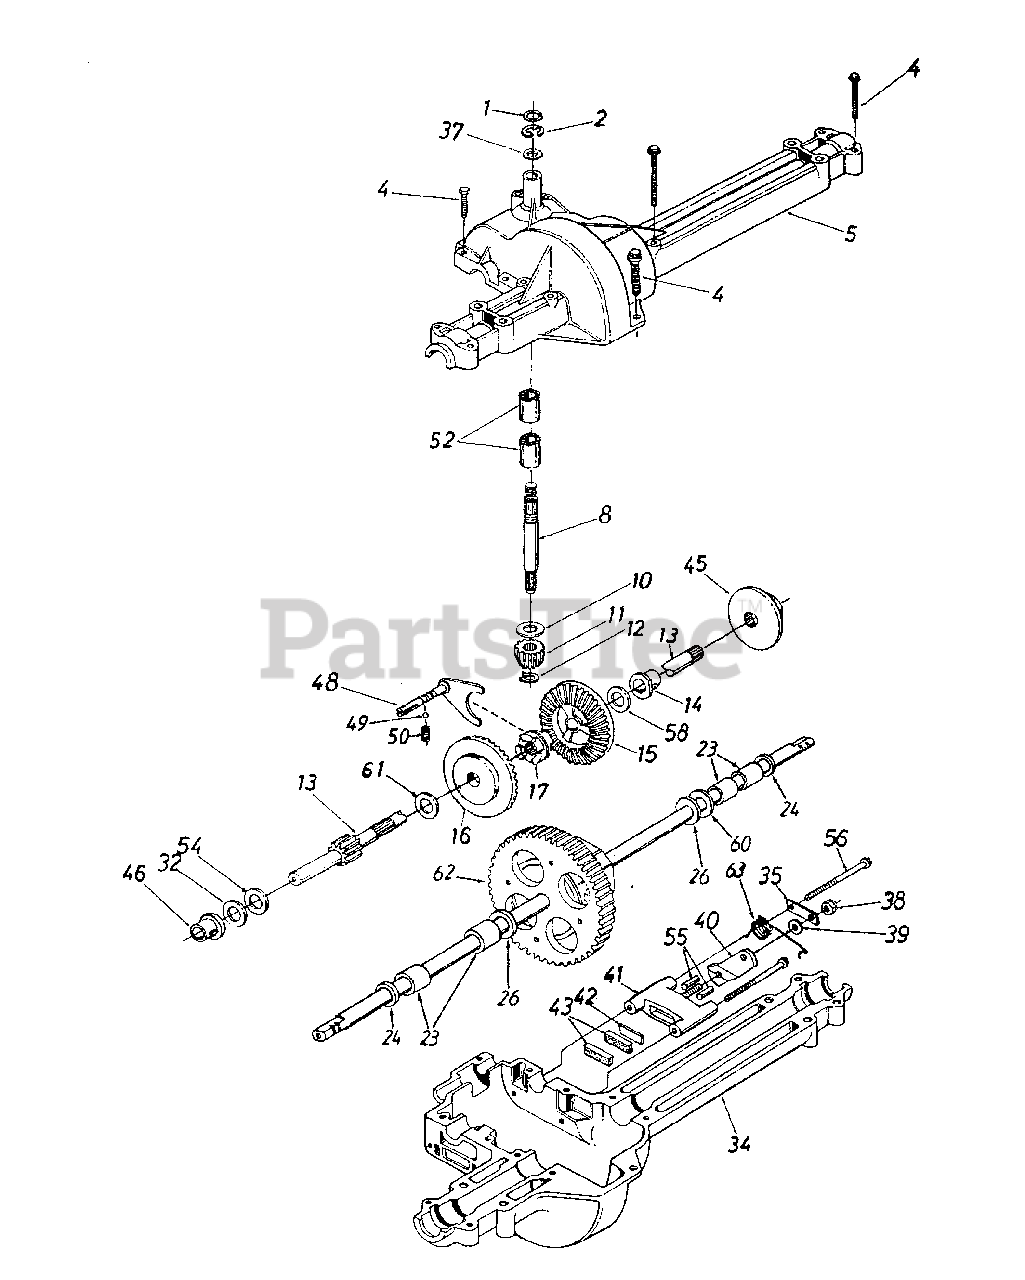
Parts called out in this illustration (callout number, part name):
1	Wire Ring
2	"E"-Ring
4	Hex Tap Scr. 1/4-20 x 1.625 Lg.
5	Upper Housing
8	Input Shaft
10	Thrust Washer 5/8" I.D. x 1.25" O.D.
11	Pinion Input 14T
12	Retaining Ring
13	Drive Shaft-R.H. Brake
14	Flange Brg. 5/8" I.D. x 314" Lg.
15	Bevel Gear 42T Small I.D.
16	Bevel Gear 42T Large I.D.
17	Clutch Collar
23	Sleeve Bearing 3/4" I.D. x 1.0" Lg.
24	Oil Seal 3/4" I.D.
26	Fl-Wash. .760" I.D. x 1.5" O.D.
32	Thrust Wash. 5/8" I.D. x 1" O.D. x .025" Thk.
32	Fl-Wash. 5/8" I.D. x 1" O.D. x .030" Thk.
32	Thrust Wash. 5/8" I.D. x 1" O.D. x .035" Thk.
32	Fl-Wash. 5/8" I.D. x 1" O.D. x .040" Thk.
34	Lower Housing
35	Anti-Rotation Brkt.
37	Fl-Wash. 5/8" I.D. x 1" O.D. x .020" Thk.
37	Fl-Wash. 5/8" I.D. x 1" O.D. x .030" Thk.
37	Fl-Wash. 5/8" I.D. x 1" O.D. x .040" Thk.
38	Hex Nut 5/16-24 Thd.
39	Fl-Wash. .344" I.D. x .875" O.D.
40	Actuating Arm
41	Brake Yoke
42	Puck Plate
43	Brake Puck
45	Brake Disc
46	Flange Bearing 5/8" I.D. x 15/16" Lg.
48	Shift Fork Ass'y.
49	Ball Detent .250" Dia.
50	Spring Detent
52	Needle Brg. 5/8" I.D. x 1/2" Lg.
54	Fl-Wash. 5/8" I.D. x 1" O.D.x .020 Thk.
55	Actuating Pin 5/16" Dia.
56	Hex Wash Hd. Self-Tap Scr. 1/4-20
58	Fl-Wash. 5/8" I.D. x 1" O.D. x.020 Thk.
60	Fl-Wash. .76" I.D. x 1.5" O.D. x .010" Thk.
60	Fl-Wash. .76" I.D. x 1.5" O.D. x .020" Thk.
60	Fl-Wash. .76" I.D. x 1.5" O.D. x .030" Thk.
60	Fl-Wash. .76" I.D. x 1.5" O.D. x .060" Thk.
61	Thrust Washer
62	Differential Ass'y.
63	R.H.-Brake Spring
